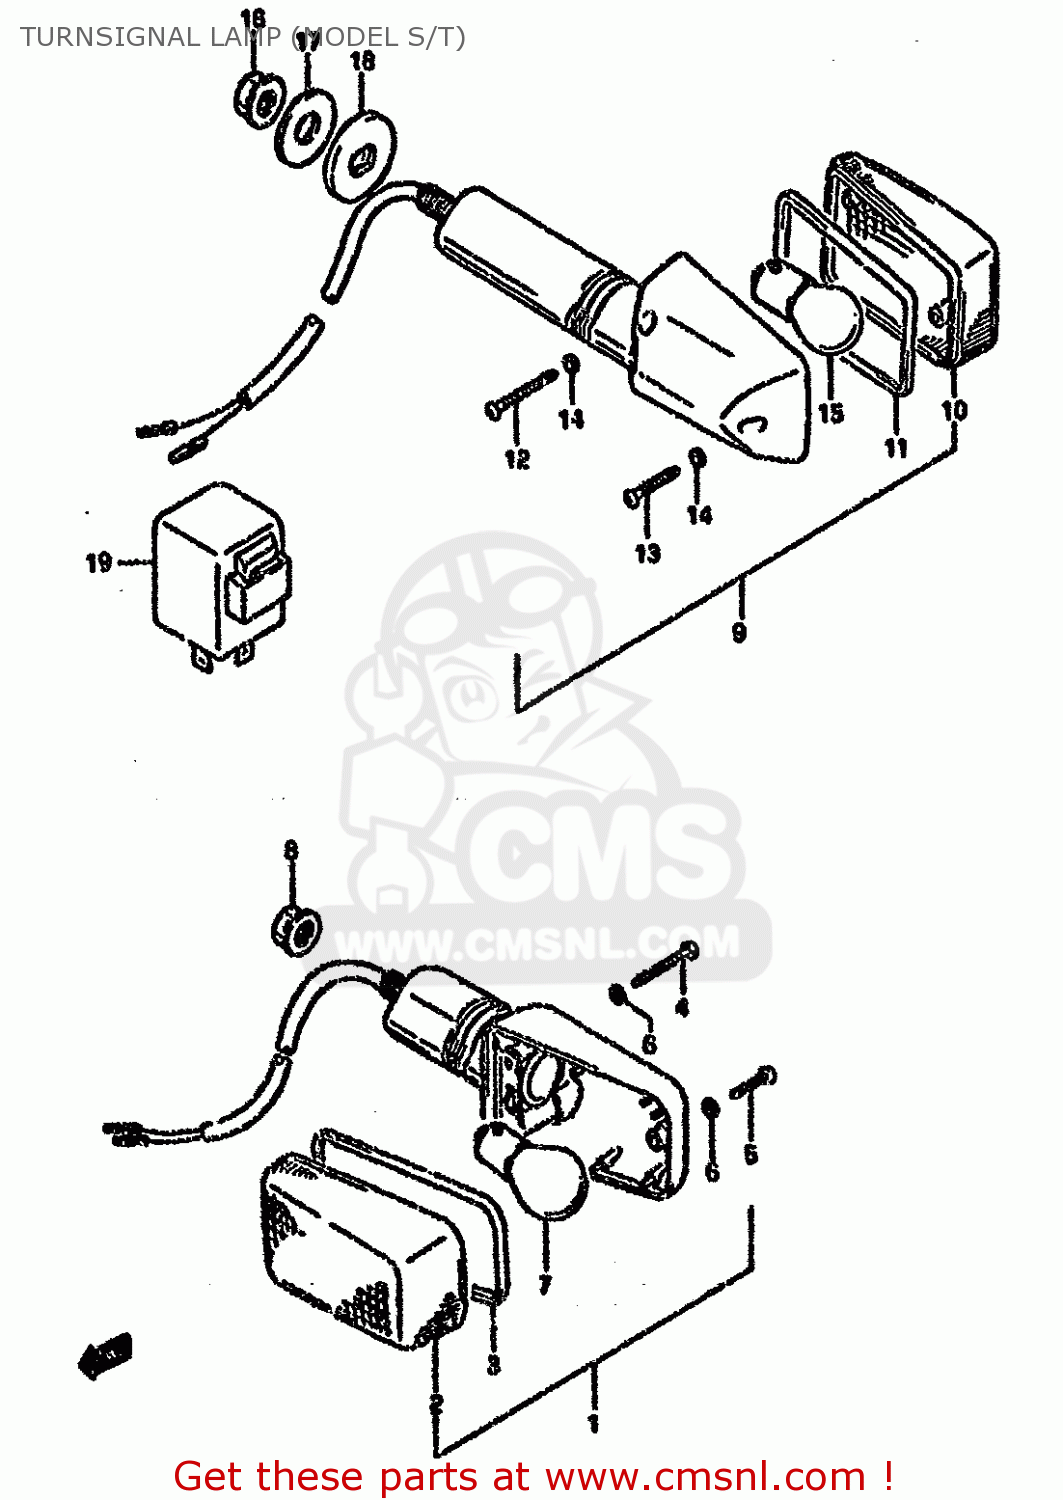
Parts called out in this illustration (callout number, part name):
1	LAMP ASSY,FR TURN SIGNAL
2	LENS
3	GASKET (NAS)
4	SCREW(3X30)
5	SCREW
6	GASKET (NAS)
7	BULB(12V21W)
8	NUT
9	LAMP ASSY,RR TURNSIGNAL
10	LENS
11	GASKET (NAS)
12	SCREW(3X30)
13	SCREW
14	GASKET (NAS)
15	BULB(12V21W)
16	NUT
17	NUT
18	WASHER(10.5X30X3.2)
19	SPACER,RR TURNSIGNAL
20	RELAY ASSY,TURNSIGNAL
21	RELAY ASSY,TUR
